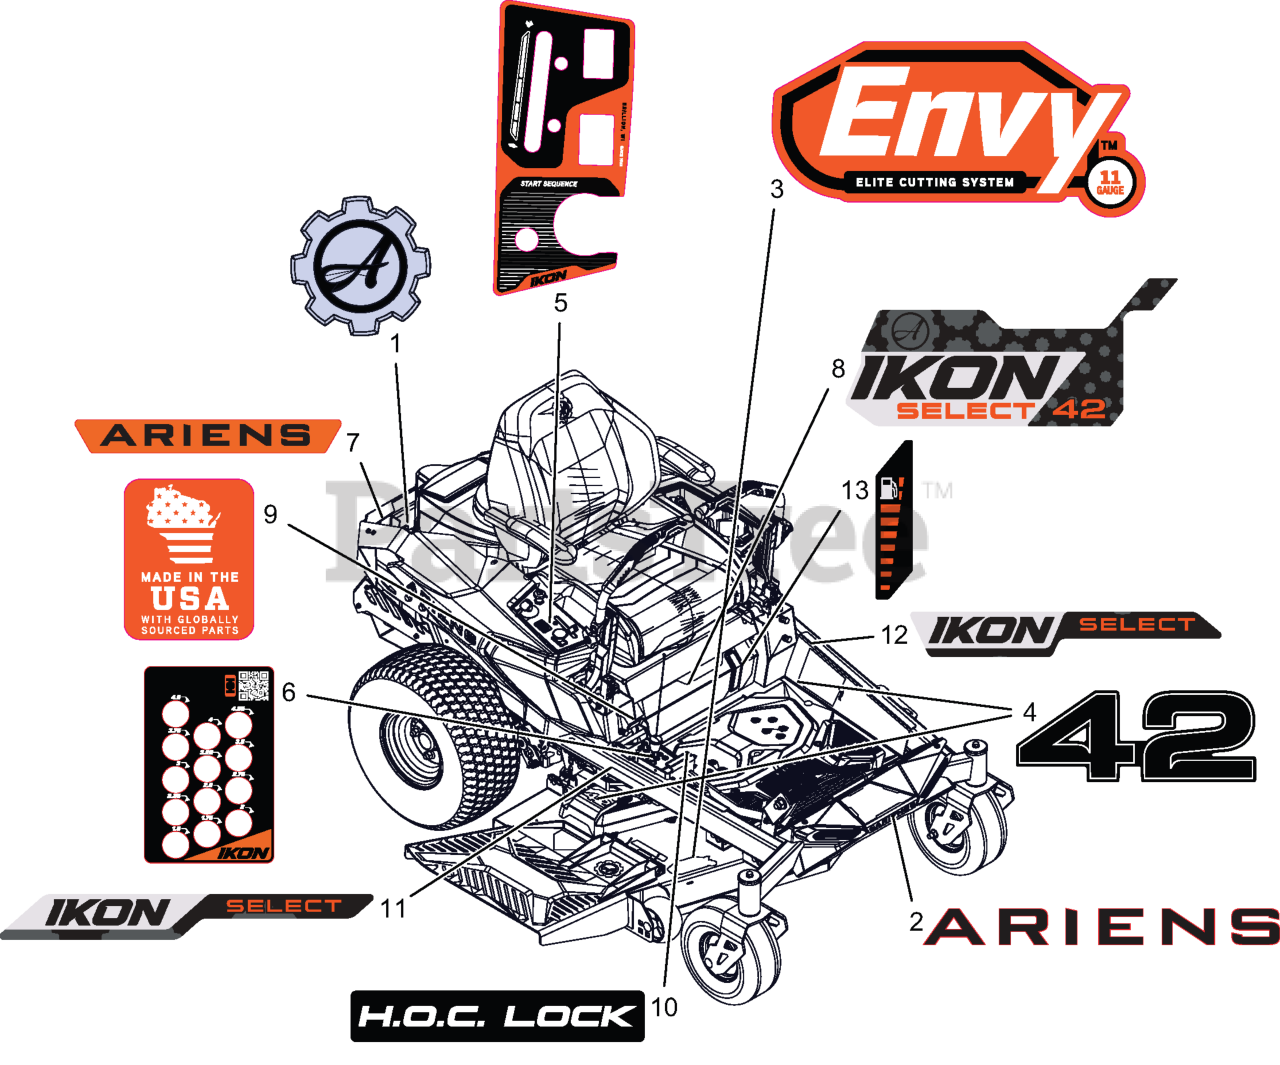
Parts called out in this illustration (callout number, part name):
1	DECAL- ARIENS GEAR BADGE
2	DECAL- ARIENS-BADGE
3	DECAL- DECK
4	DECAL- 42
5	DECAL- CONTROL PANEL
6	DECAL- HEIGHT OF CUT
7	DECAL- ARIENS
8	DECAL- IKON 42 KICKPLATE-P
9	DECAL- MADE IN USA
10	DECAL, HOC LOCK
11	DECAL, IKON SELECT FRAME - RH
12	DECAL, IKON SELECT FRAME - LH
13	DECAL, FUEL LEVEL - IKON SELECT
